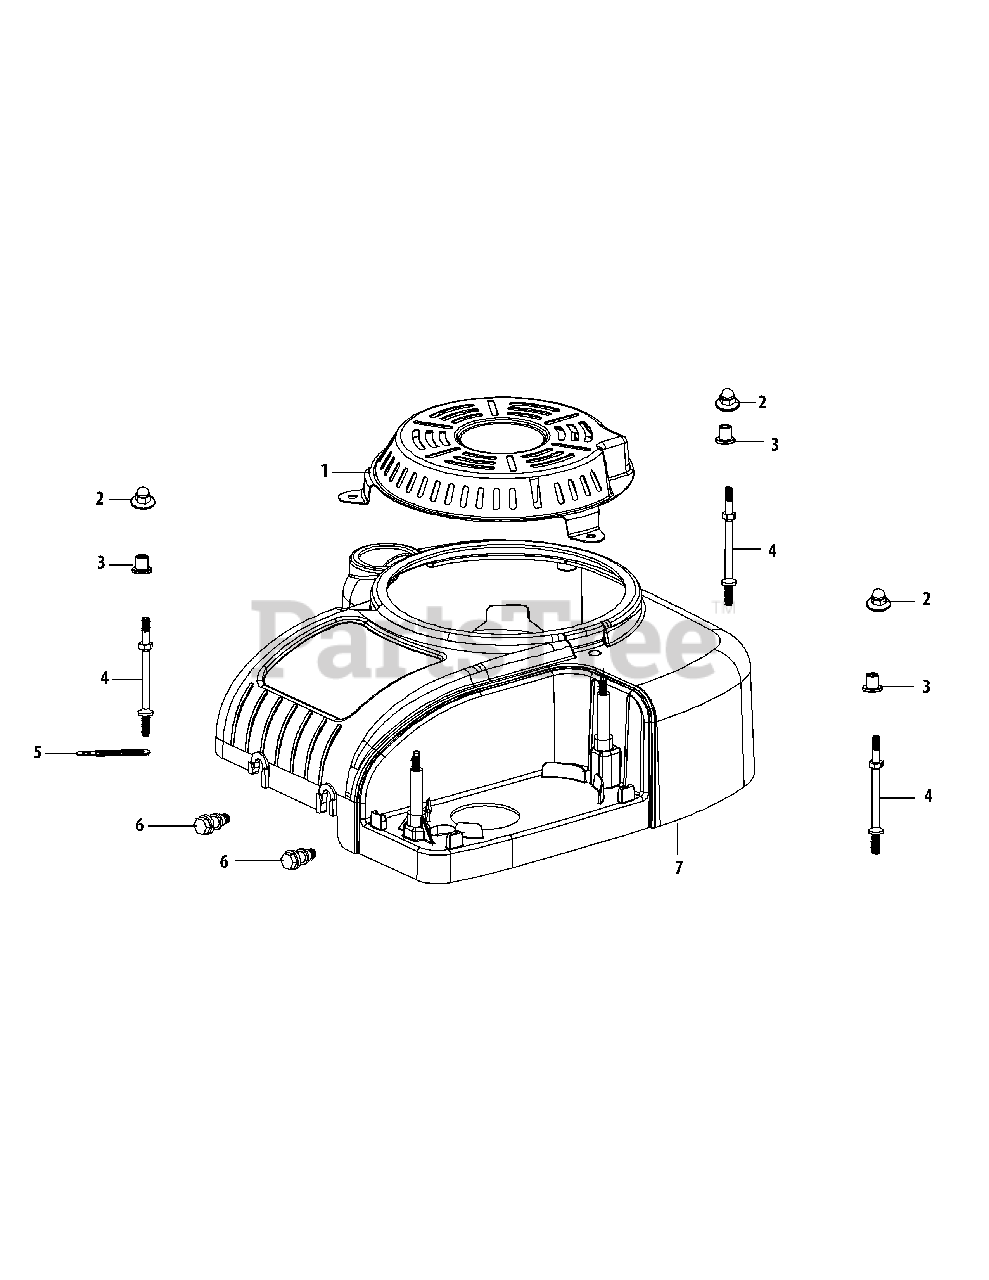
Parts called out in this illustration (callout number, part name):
3	Engine Shroud Spacer
4	Starter / Shroud Stud M6×100
5	Flexible Clamp
7	Air Shield
